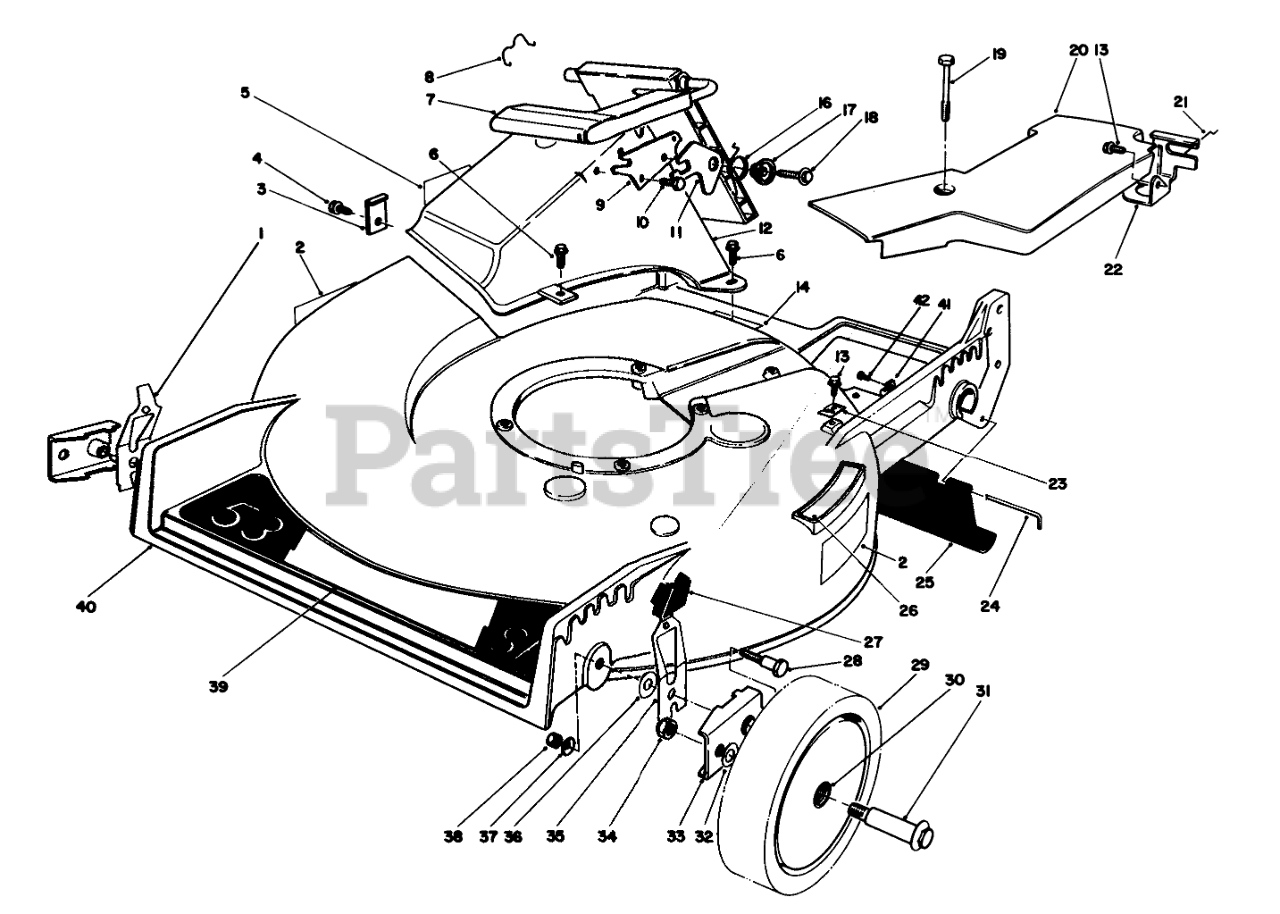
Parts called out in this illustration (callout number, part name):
1	R HP SPRING ARM ASM
2	Decal Danger
3	TUNNEL CLIP
4	SCREW
5	DECAL - DANGER
6	SCREW-HWH
7	Discharge Door Assembly
8	DOOR RET SPRING
9	DOOR LATCH PLATE
10	SCREW-PLASTITE
11	SAFETY LATCH
12	Tunnel-Discharge (Incl. Ref. #5)
13	SCREW-HWHTF
14	Decal
16	TORSION SPRING
17	DOOR SPACER
18	SCREW-HWH
19	SCREW-HHFTF
20	Belt Cover
21	RETAINER-CABLE
22	Bracket-Traction Adj.
23	CLAMP-CABLE
24	ROD-SHIELD
25	SHIELD-TRAILING
26	DECAL - STEP PAD INT'L
27	KNOB-ARM
28	PIVOT SCREW
29	Wheel & Tire Assembly (Incl. Ref. #30)
30	BUSHING
31	BOLT-WHEEL
32	WASHER
33	HP PIVOT ARM ASM
34	Nut
35	L. HP SPRING ARM ASM
36	WASHER-PIVOT
37	WASHER-BELLEVILLE
38	NUT-LOCK, NI
39	Decal-53
40	Housing (Incl. Ref. #2 & 26)
41	CLAMP-CABLE
42	SCREW
